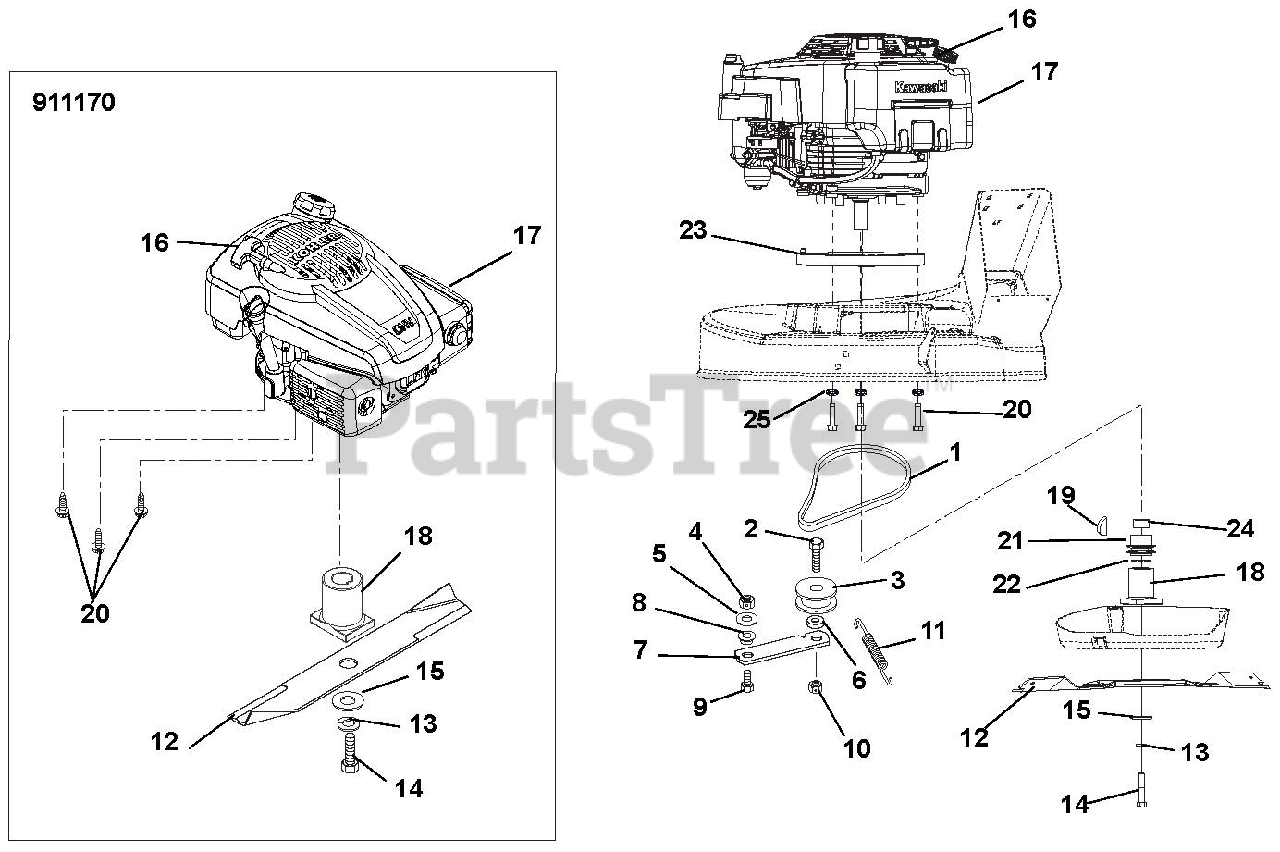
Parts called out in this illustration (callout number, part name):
1	V-BELT, 3L-COGGED
2	@BLT-HEX .44-14X1.50 GR5 YWZC
3	IDLER-FLAT 1.75 X .47
4	@NUT-LK-CTR .31-18 YWZC
5	@WSHR-FL-STL.344X.688X.065YWZC
6	BSHG-SLV .469 X .750 X .430
7	IDLER ARM
8	BSHG-FLG .325X.501X.250X1.120
9	@BLT-HEX .31-18X.75 GR5 YWZC
10	@NUT-LK-CTR .44-14 YWZC
11	SG-TENS .043X.44X3.31 WLD 5.8
12	21" MOWER BLADE
13	@WSHR-LK .38X.094 REG YWZC
14	BLT-HEX .38-24 X 2.00 GR8 YWZC
14	BLT-HEX .38-24 X 2.75 GR8 YWZC
15	WSHR-FL-STL .390X1.5X.125 YWZC
16	HANDLE, RECOIL START
17	ENGINE, KOHLER XT775 50 STATE
17	ENGINE,KAWI FJ180 PRO-50 STATE
18	ADAPTER, CE BLADE
18	ADAPTER, BLADE - KAWI KYMCO
19	KEY-WDRF .156X.625X.25 SAE 6
20	@SCR-TAP .38-16X1.00 HWH TR YZ
20	@SCR-TAP .38-16X1.75 HWH TR YZ
21	PULLEY, CRANK - KAWI KYMCO
22	WASHER-WAVE .885X1.311X.125
23	PLATE, ENGINE SHIM - CAST
24	SPACER, .875 X 1.125 X .525
25	SPACER,.75 X .515 X .12
